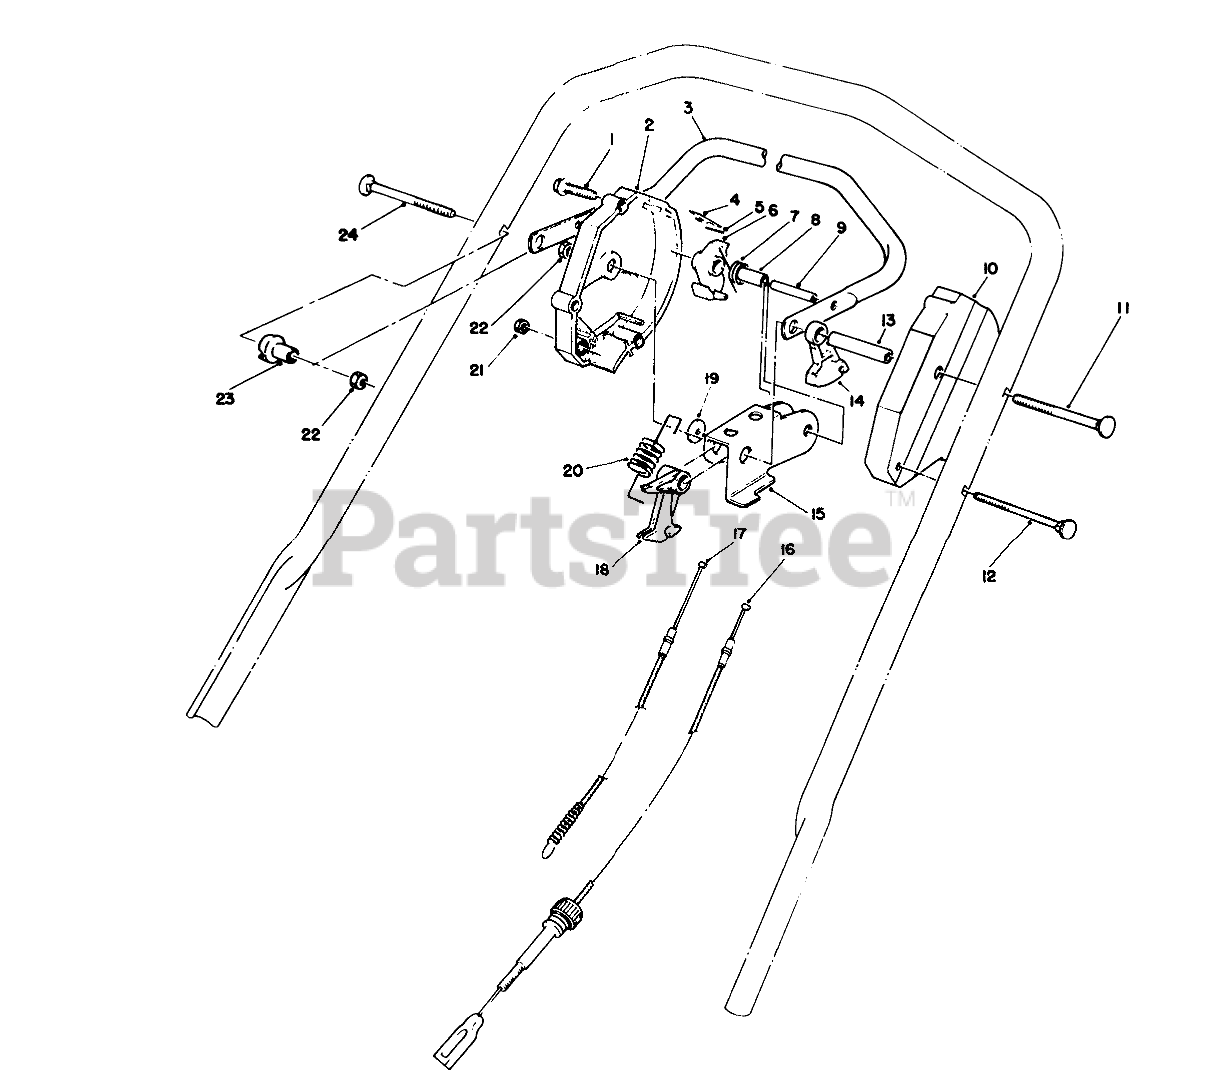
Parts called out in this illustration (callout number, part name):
1	SCREW-HWHTF
2	Housing-Control R.H. (Incl Ref. #4 & 5)
3	Bar-Control
4	SPRING-LEAF
5	PIN-INSERT
6	HOOK-CONTROL
7	SPRING-TORSION
8	SPACER
9	PIN-ROLL, SLOTTED
10	HOUSING-CONTROL, LH
11	5/16-18 X 3 HNDLE SCREW
12	HANDLE SCREW
13	TUBING-SPACER
14	LEVER-TRACTION
15	ROCKER
16	TRACTION CABLE
17	CLUTCH CABLE
18	LEVER-CABLE
19	WASHER-NYLON
20	SPRING-DETENT
21	NUT-HEX
22	NUT-LOCK, NI
23	SPACER-SUPPORT
24	5/16-18 X 2 HNDLE SCREW
